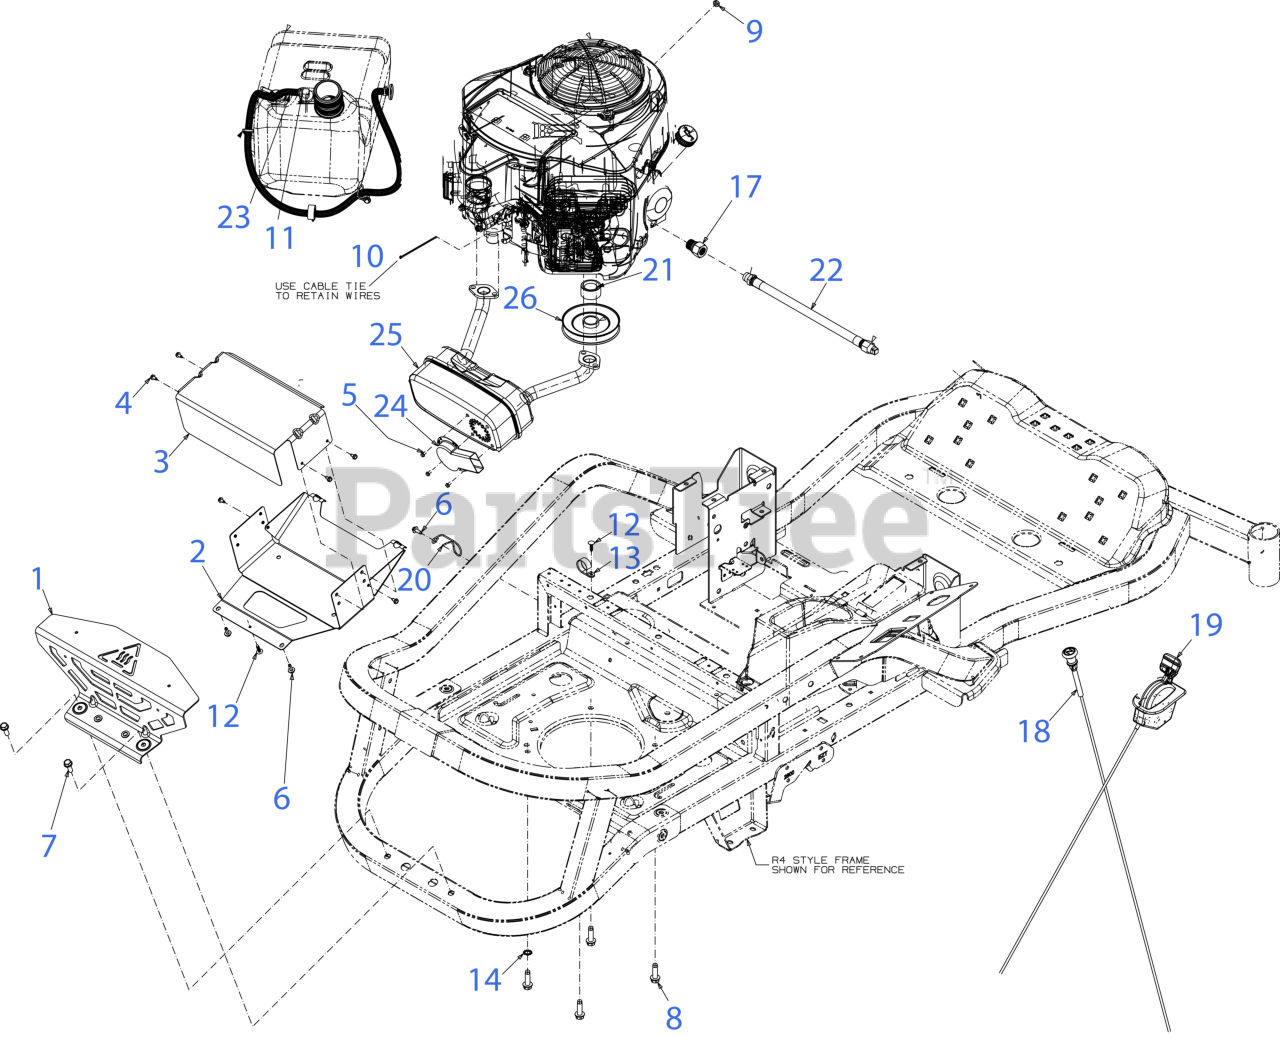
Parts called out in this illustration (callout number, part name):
1	MUFFLER COVER (REAR) (BLACK)
2	MUFFLER SHIELD (LOWER)
3	MUFFLER SHIELD (TOP)
4	HEX SCREW AB-TAP #10 x .50
5	HEX SCREW WASHER HD #8-18 x 0.500
6	SCREW M6-1 x .625
7	SCREW 5/16-18 x .875 GR5
8	SCREW 3/8-16 X1.250
9	HEX NUT 1/4-20
10	CABLE TIE
11	HOSE CLAMP 1/20
12	RATCHET CLIP (.188 x .85)
13	DRAIN HOSE CLAMP
14	LOCK WASHER 3/8
17	OIL DRAIN FITTING (M20x2.5)
18	CHOKE CABLE 41"
19	THROTTLE CABLE 38.5LG
20	HOSE GUIDE
21	ENGINE PULLEY SPACER
22	OIL DRAIN HOSE
23	FUEL HOSE LOW PERMEATION 36"
24	EXHAUST DELECTOR (LONG)
25	EXHAUST MUFFLER
26	TRANSMISSION DRIVE PULLEY
